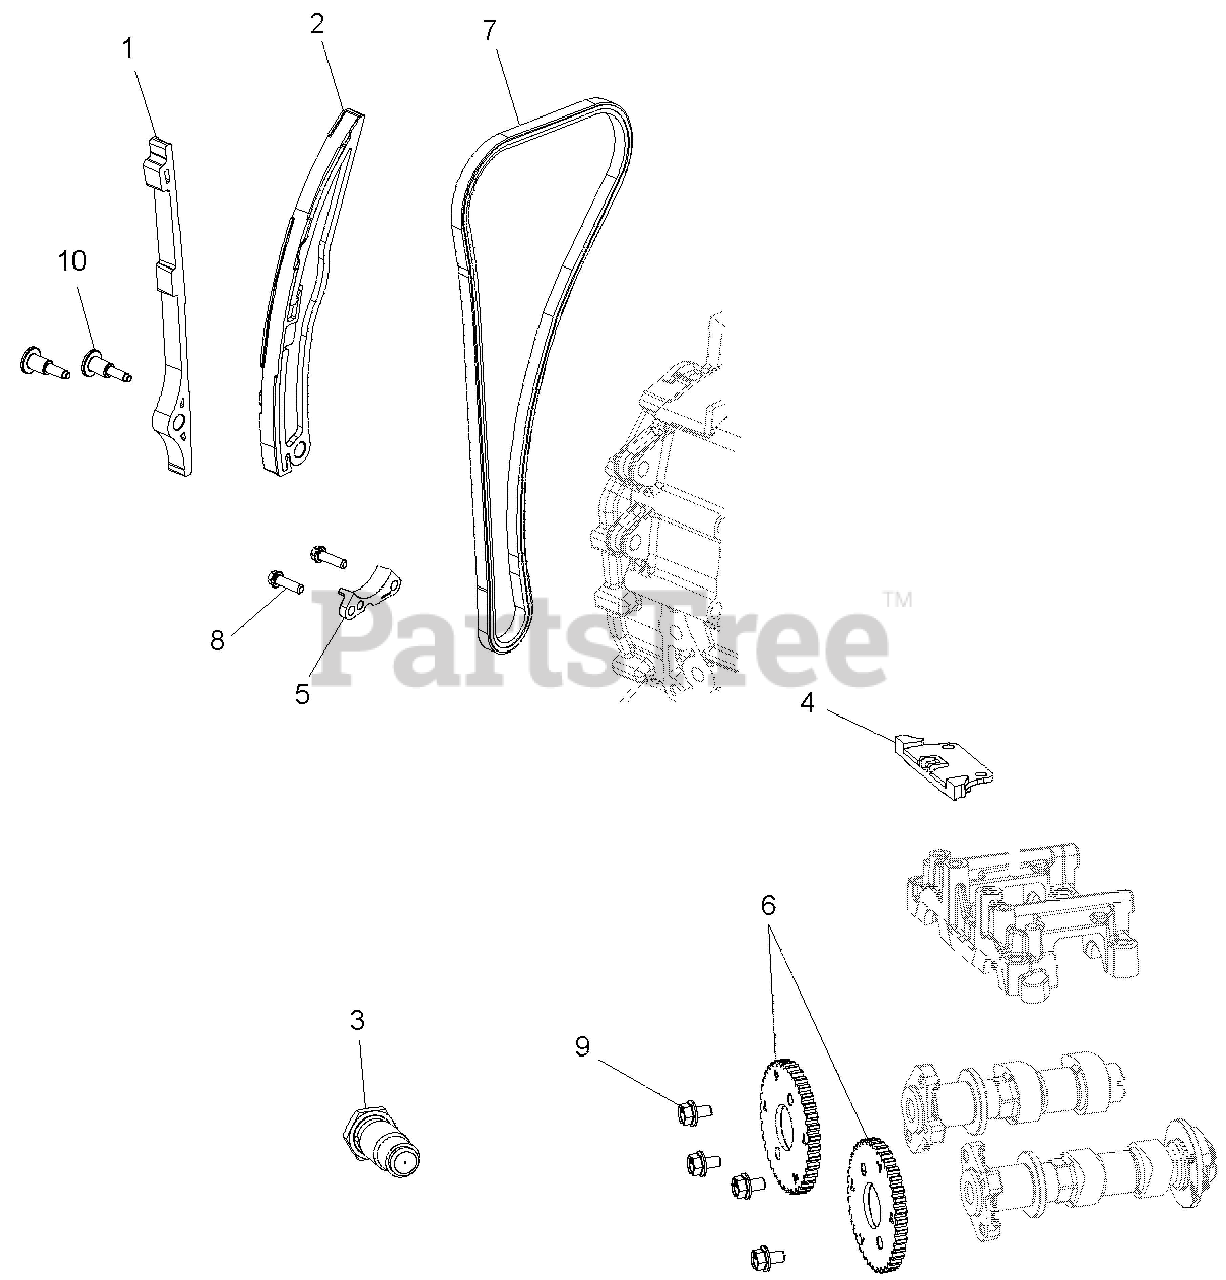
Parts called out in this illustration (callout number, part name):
1	GUIDE-CAMCHAIN,FIXED
2	GUIDE-CAMCHAIN,TENSIONER
3	TENSIONER-CAMCHAIN,HYD
3	GASKET-TENSIONER
4	GUIDE, CAMCHAIN, FIXED, COVER
5	GUIDE-CAM DRIVE,LOWER
6	SPROCKET, CAM, DRIVEN
7	CHAIN-CAMSHAFT 144L
8	SCR-M6X20,HXFLG,0600214
9	SCR-HXFL,M6X1.0X10 10.9
10	BOLT-SHLDR,M6X12X15
